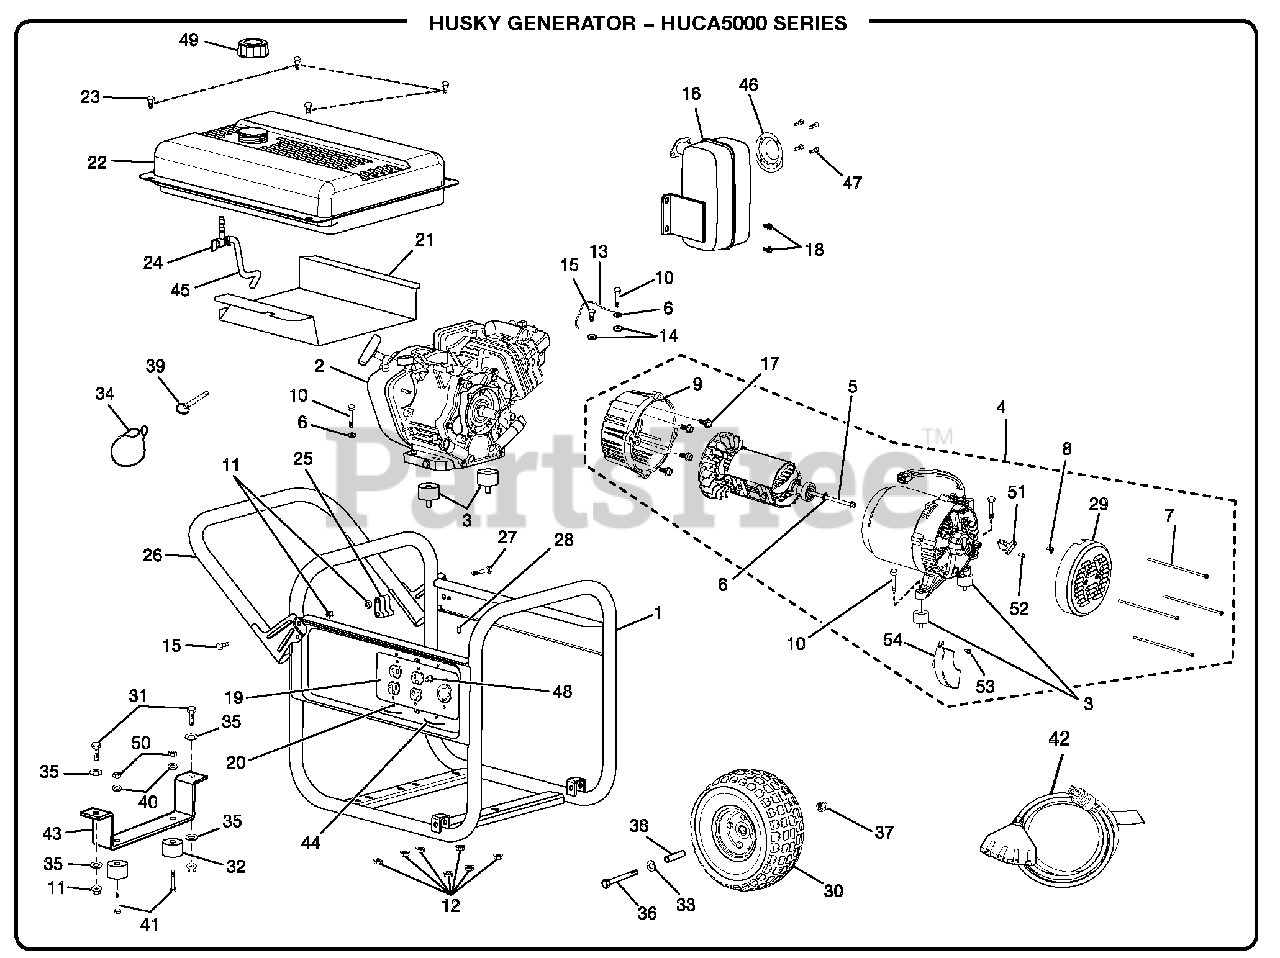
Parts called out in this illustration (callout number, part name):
1	Frame Assembly
2	Engine (Subaru OHC)
4	Generator Head Assembly (Inc. Key No. 7, 9, 29, and 51-54)
5	Bolt (5/16-24 x 6-5/8 in., Hex Hd.)
6	Lock Washer (5/16 in.)
7	Bolt (1/4-20 x 6 in., Hex Hd.)
8	Ground Lug
9	Adapter Housing
10	Bolt (5/16-18 x 1-1/2 in.)
11	Lock Nut (5/16-18)
12	Flange Nut (5/16-18)
13	Ground Wire Assembly
14	Washer (5/16 in., External Star)
15	Bolt (5/16-18 x 3/4 in., Hex. Hd.)
17	Bolt (3/8-16 x 3/4 in.)
18	Bolt (5/16-24 x 5/8 in.)
19	Wire Panel
20	Screw (6-19 x 1/2 in.)
21	Heat Shield
22	Fuel Tank Assembly
23	Screw (#10 x 1 in.)
24	Fuel Shut Off Valve with Filter
25	Handle Lock Bracket
26	Handle Assembly
27	Bolt (5/16-18 x 2-1/4 in.)
28	Rubber Cap
29	End Bell Cover
31	Bolt (5/16-18 x 1 in.)
32	Rubber Foot
33	Washer (3/8 in.)
35	Washer (5/16 in.)
36	Bolt (3/8-16 x 4-1/4 in.)
37	Lock Nut (3/8-16)
38	Spacer (.38 ID)
39	Handle Lock Pin
40	Washer (1/4 in.)
41	Bolt (1/4-20 x 1-1/2 in.)
42	Extension Cord (25 foot, 20 amp)
43	Frame Support
44	Cord Retainer
45	Fuel Line Assembly
46	Spark Arrester Screen
47	Screw (8-32 x 3/8 in.)
48	Circuit Breaker (20 amp)
50	Lock Nut (1/4-20)
51	Brush Assembly Kit
52	Bolt, Mounting Brush Assembly
53	Bolt, AVR Mounting
54	Automatic Voltage Regulator (5000 Watt)
